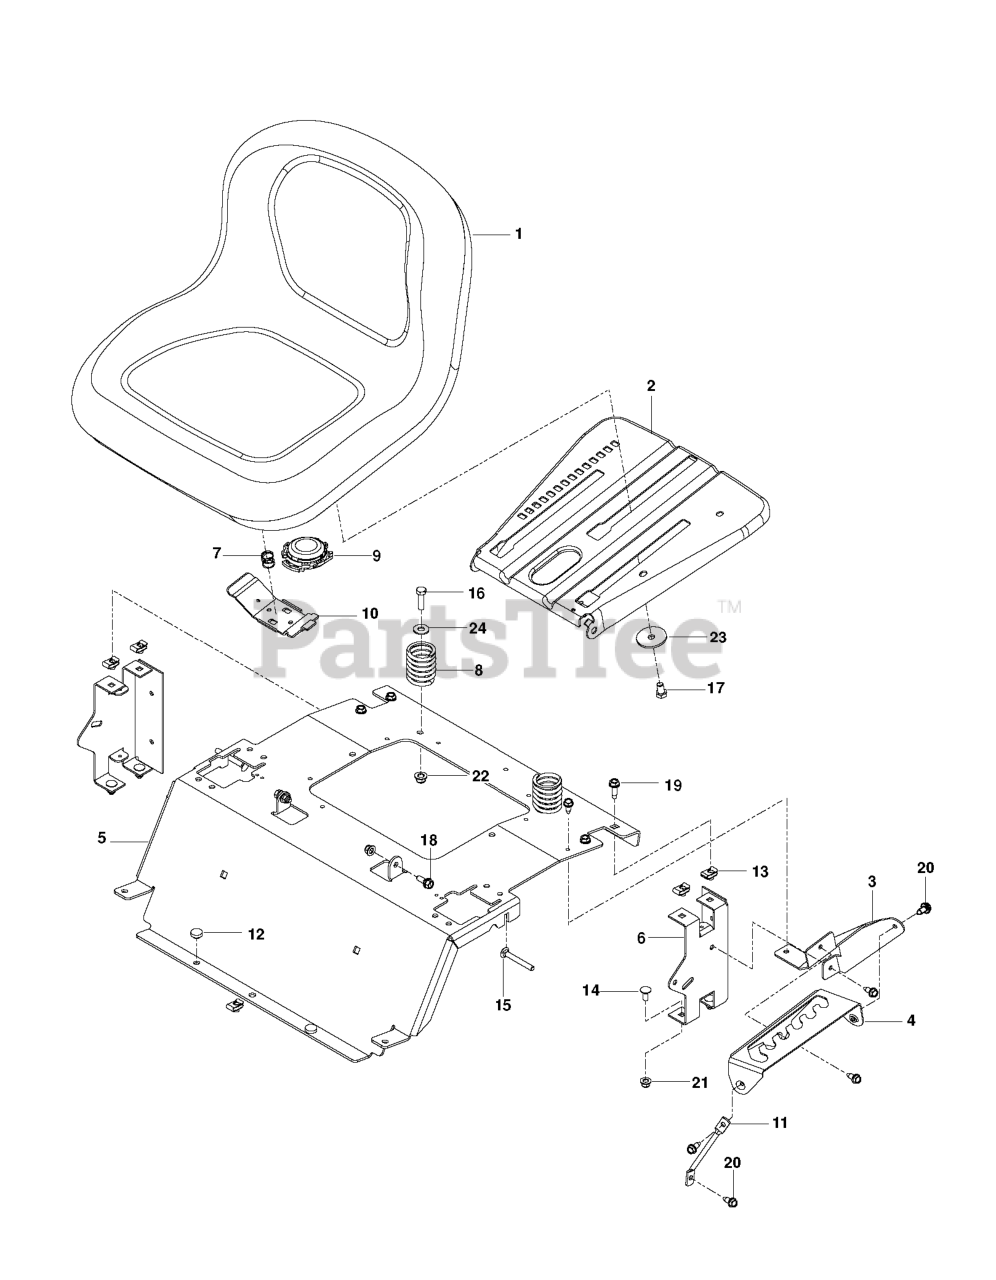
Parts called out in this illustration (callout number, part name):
1	SEAT.TH150.MS498.GRY.HUSQ.TEX
2	PAN.ASM.SEAT.3PT
3	PLATE.SUPPORT.DECK.LIFT.X431
4	PLATE.DECK.LIFT.X431
5	SUPPORT SEAT ORANGE
6	SUPPORT REAR SEAT BLACK
7	SPRING.LATCH.SEAT.TEX
8	SPRING COMPRESSION
9	SWITCH.SEAT.OPC.GRY.BUTTON/CAP
10	HANDLE.SLIDE.SEAT.TEX.BLACK
11	SUPPORT.LEG.DECK.LIFT
12	GROMMET.BUMPER
13	U-CLIP 5/16-18 NUT RETAINER
14	RP BOLT 5/16-18 X3/4 ZN/YEL GR
15	RHSNB 5/16-18 X 2-1/2 GR5 ZD
16	BOLT
17	HCS 3/8-16 X 5/8 GR 5 ZD
18	BOLT, SHOULDER
19	SCREW.THDROL.5/16-18X3/4.TTY
20	BOLT.5/16HEX.WHS.HD
21	5/16-18 NYLOC FLANGE NUT
22	NUT 3/8-16 HEX FLG NYLOC ZD
23	WASHER, 3/8 SPEC
24	RP WASHER 3/8 FLAT
